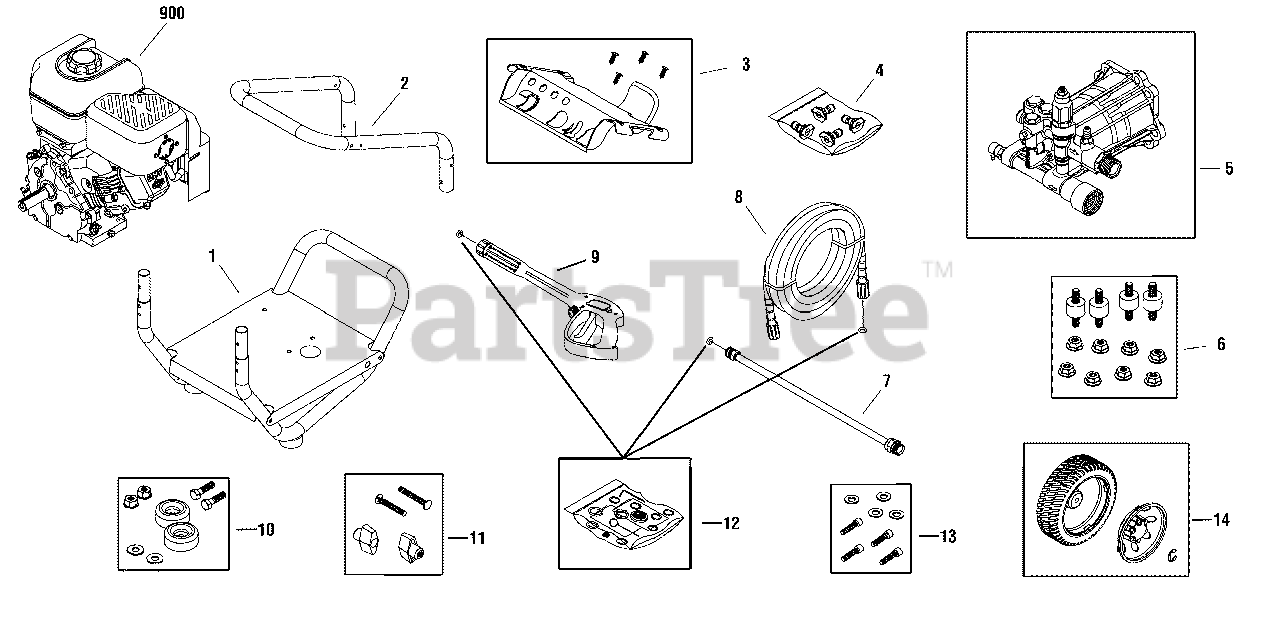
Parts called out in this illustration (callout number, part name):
6	KIT, Vibration Mount
8	HOSE
9	GUN
10	MOUNT, Vibration
11	KIT, Hardware Handle
12	KIT, O-Ring
13	KIT, Hardware Pump Mounting
900	* ENGINE
